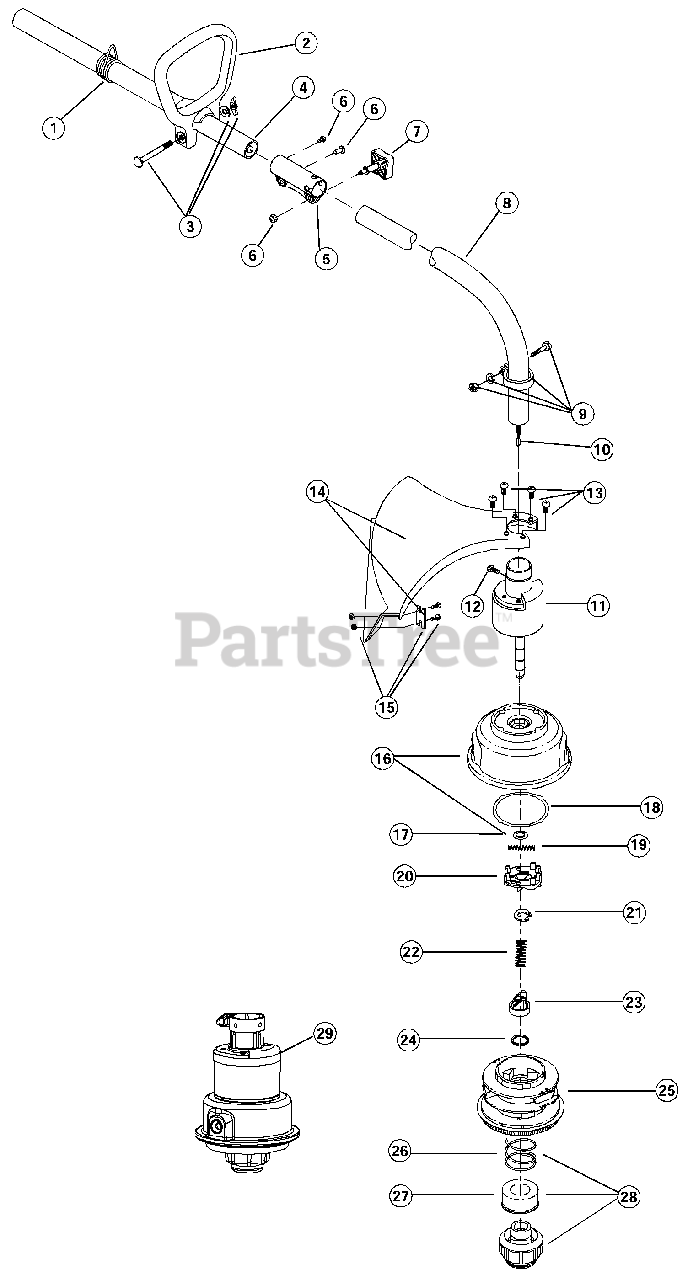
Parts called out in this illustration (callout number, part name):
1	Shoulder Harness Clamp
2	D-Handle
3	D-Handle Hardware Assembly
4	Upper Drive Shaft Housing Assembly
5	EZ-Link Coupler
6	EZ-Link Hardware
7	Adjustment Knob
8	Lower Drive Shaft Housing Assembly
9	Lower Clamp Assembly
10	Flexible Drive Shaft
11	Bushing Housing Assembly w/shaft
12	Anti-Rotation Screw
13	Guard Mounting Screws
14	Guard and Blade Assembly
15	Blade Assembly
16	Outer Spool and Eyelet Assembly w/ Retainer
18	Thrust Washer
19	Small Spring
25	Inner Reel
26	Large Spring
28	Bump Head Knob Assembly w/Spring & Foam Seal
29	Complete Cutting Head Assembly
